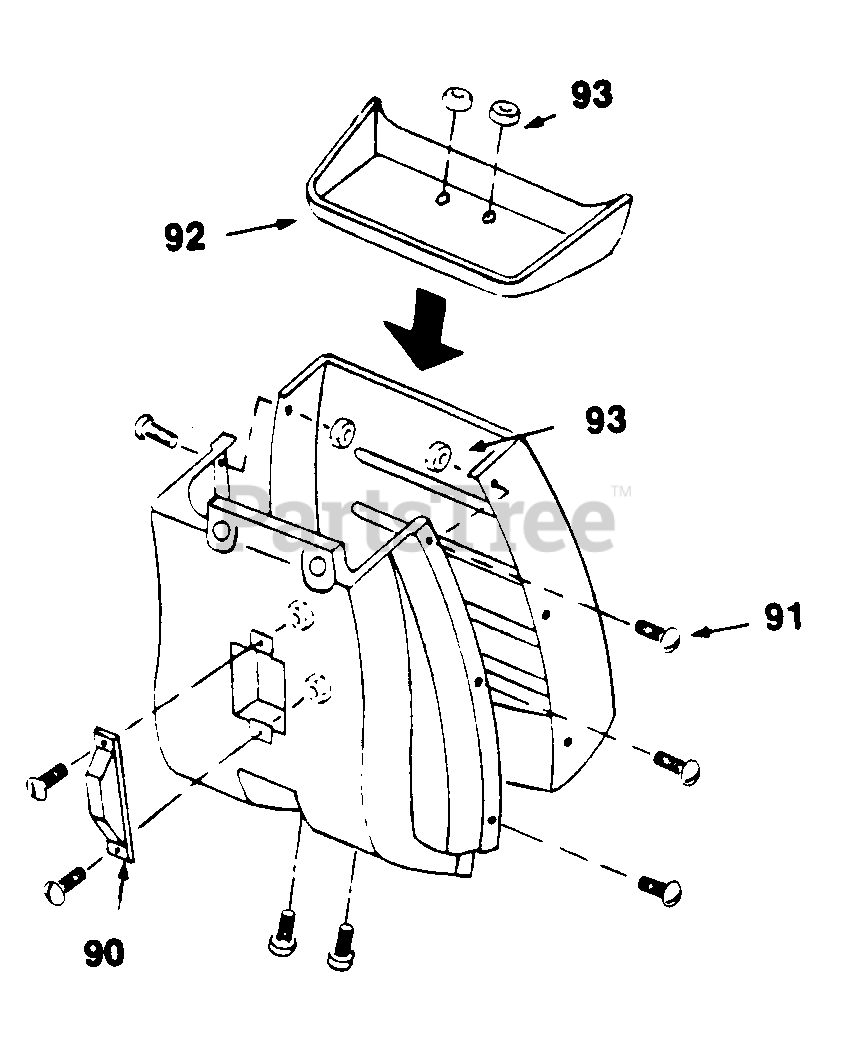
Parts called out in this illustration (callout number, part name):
90	Handle-Plastic
91	Screw #10 x 5/8 Machine
92	Baffle-Catcher
93	Nut #10-32 Hex Keps
